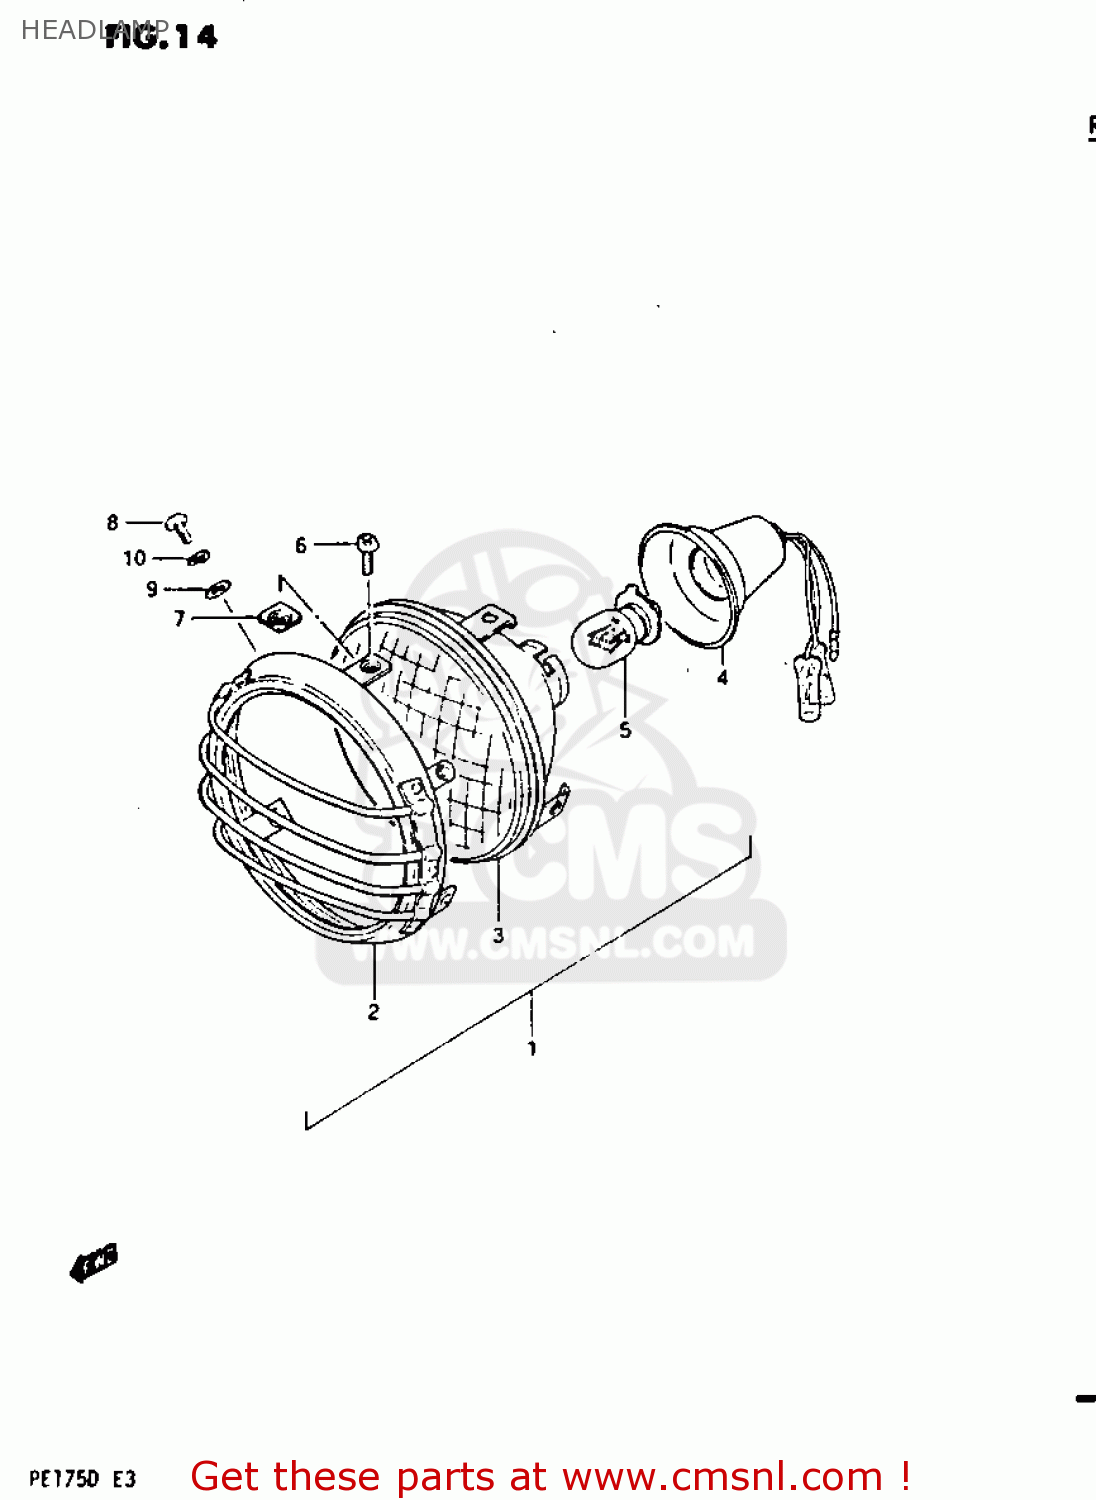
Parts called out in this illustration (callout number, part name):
1	LAMP ASSEMBLY,HEAD
2	RIM,HEADLAMP
3	LAMP UNIT
4	SOCKET,HEADLAMP
5	BULB(6V15/15W/STANLEY,A3598HA)
6	SCREW
7	NUT
8	SCREW
9	WASHER 4MM
10	WASHER,LOCK 4M
